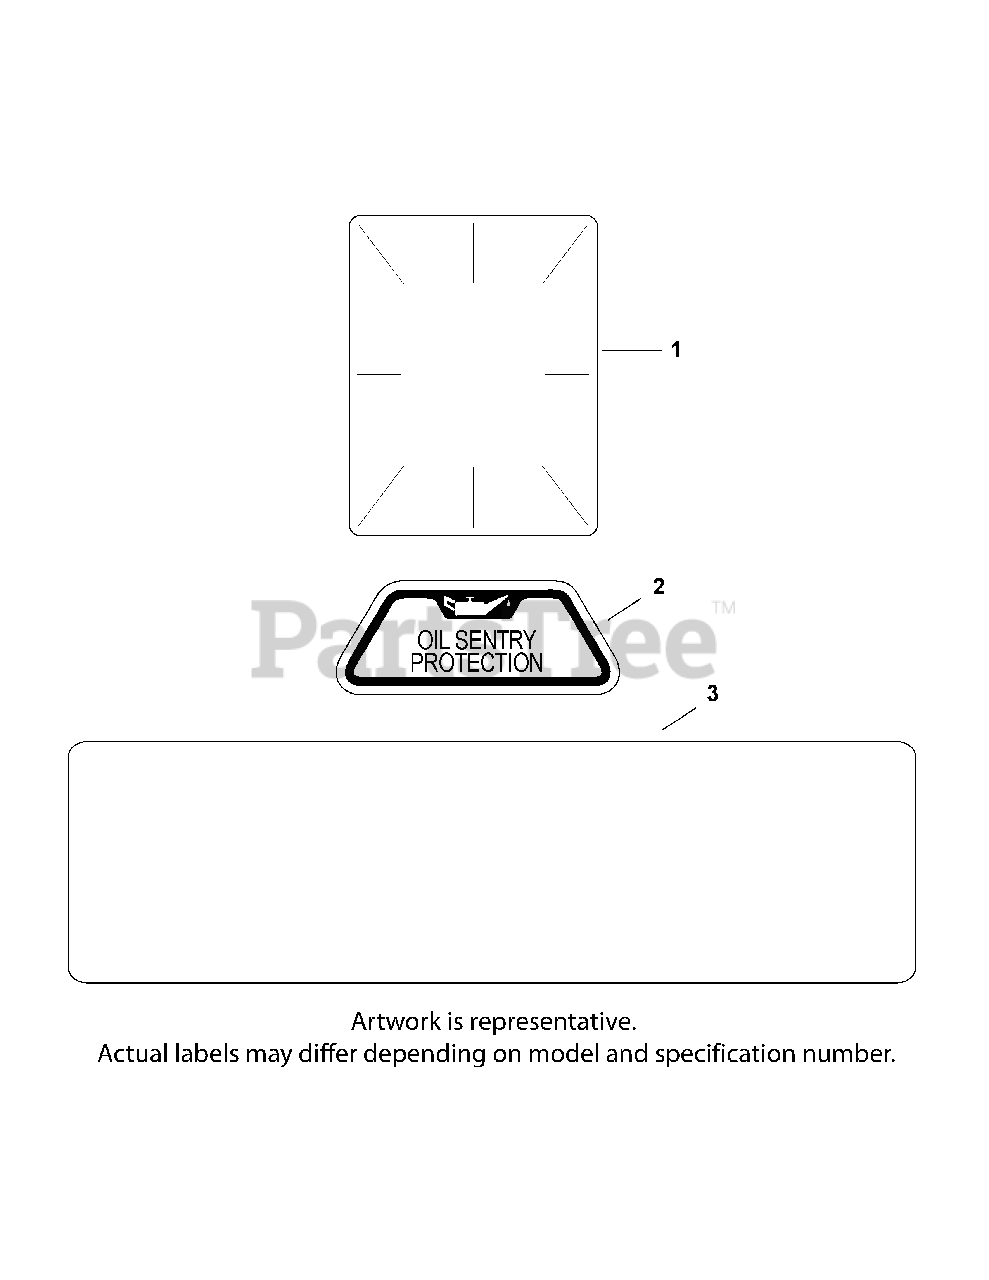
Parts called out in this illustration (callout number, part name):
1	Decal, Clear Laminate
2	Decal, Oil Sentry
3	Decal,HP (23)
